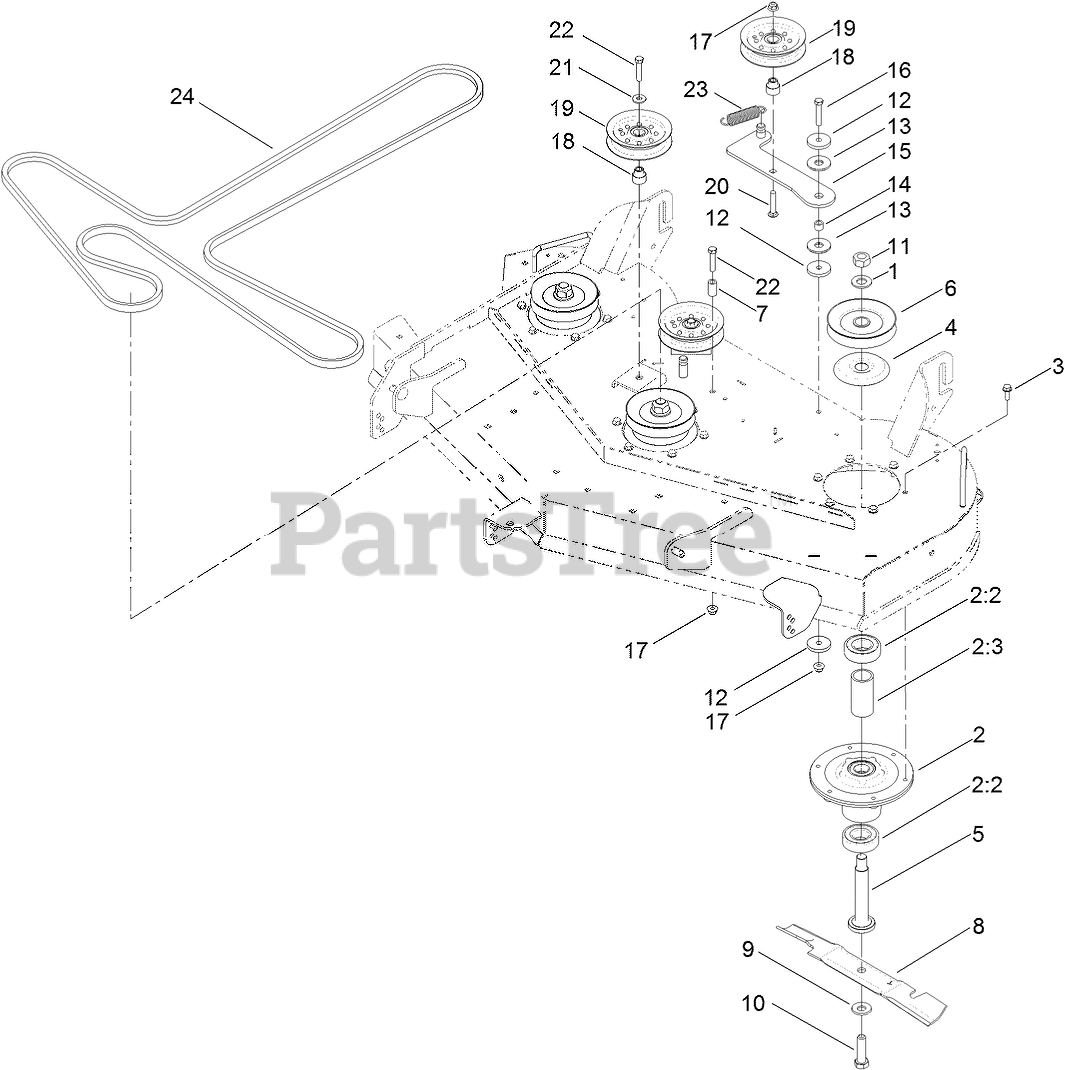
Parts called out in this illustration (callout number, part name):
1	WASHER
2	SPINDLE ASM
2:2	BEARING-BALL
2:3	SPACER-BEARING
3	SCREW-TAPTITE
4	SHIELD-BEARING
5	SHAFT-SPINDLE
6	PULLEY
7	SPACER
8	BLADE-MULCH, 16.50 INCH
9	WASHER-BELLEVILLE
10	SCREW-BLADE
11	NUT-HEX
12	WASHER-PLAIN
13	WASHER-FRICTION, COMPOSITE
14	BUSHING-LEVER, LIFT
15	ARM-IDLER
16	SCREW-HH
17	NUT-HF, NI
18	BUSHING-IDLER
19	PULLEY-IDLER
20	SCREW-CARR
21	WASHER-HARDENED
22	SCREW-HH
23	SPRING-EXTENSION
24	V-BELT
